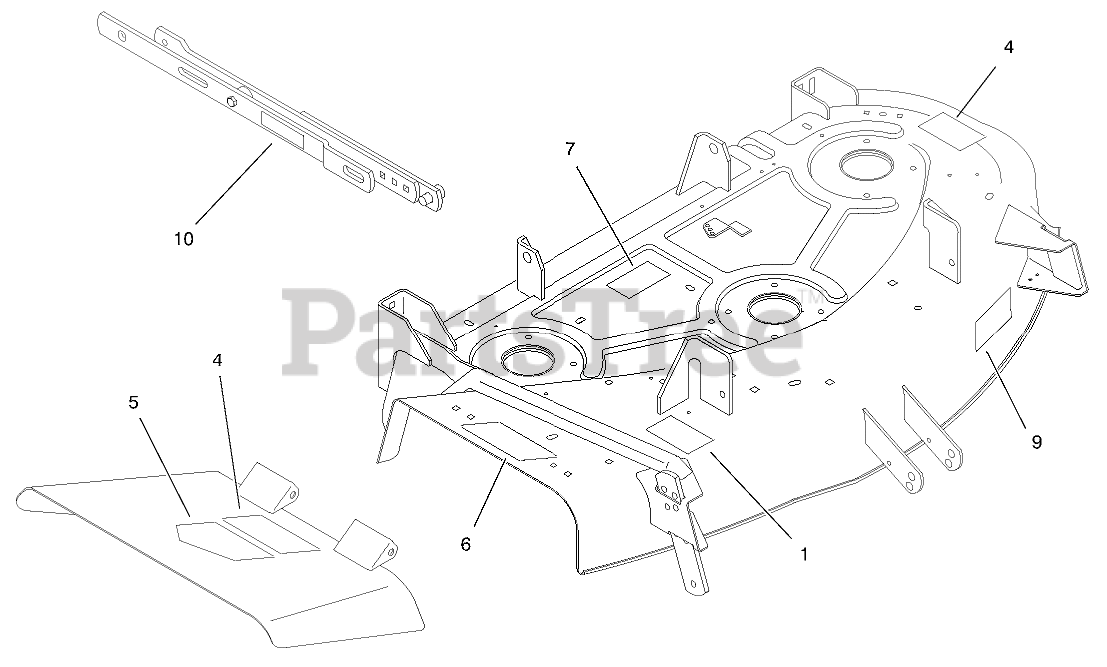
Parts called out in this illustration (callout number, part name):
1	DECAL-BELT ROUTING
4	DECAL-DANGER
5	DECAL-DANGER
6	DECAL-DANGER
7	DECAL - BELT ROUTING
9	DECAL-ADJUSTMENT, WHEEL
10	DECAL-WARNING
